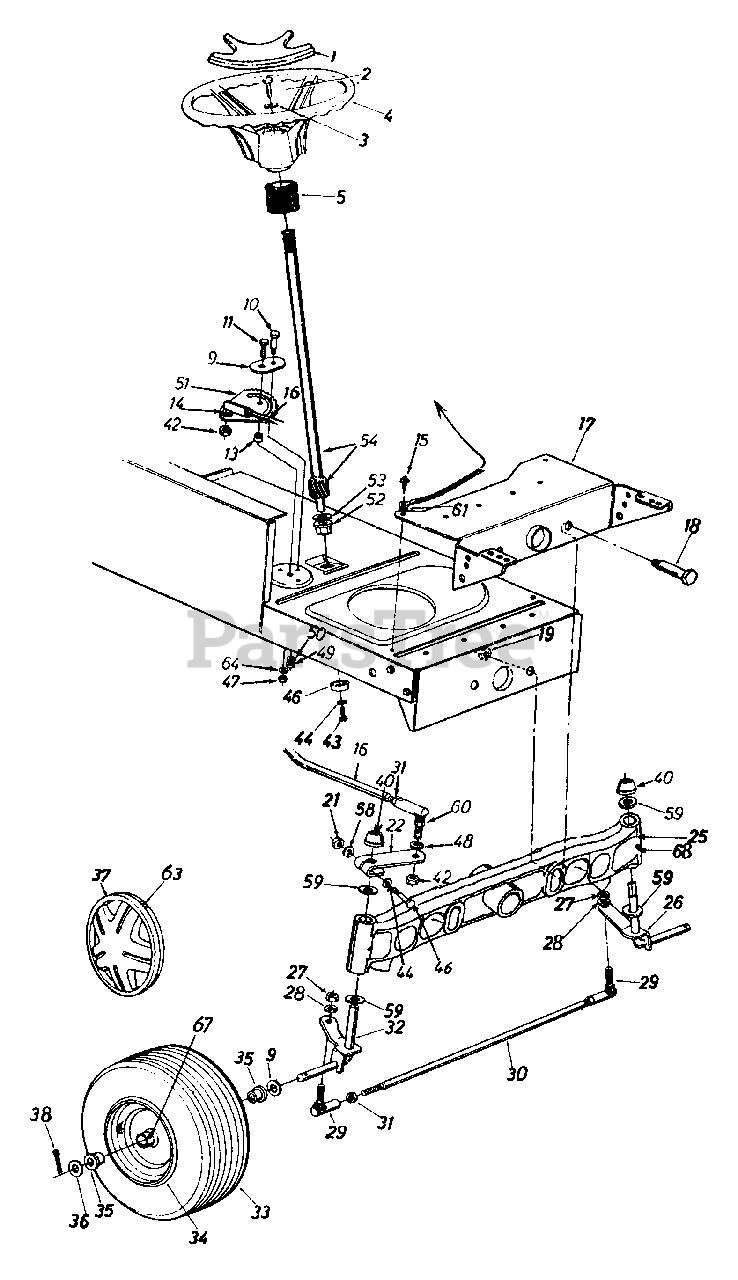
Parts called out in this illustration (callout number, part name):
1	Steering Wheel Cap
2	Hex Bolt 5/16-18 x 1" Lg.
3	Belleville Wash. .345" I.D.
4	Steering Wheel
5	Steering Bellow - 9"
9	Retainer Plate
10	Shoulder Bolt .437" Dia. x .35" Lg. - 5/16-18 Thd.
11	Hex Bolt 3/8-24 x 1.0" Lg. (Grade 5)
13	Spacer .380" I.D. x .625" O.D. x .227
14	L-Wash. 3/8" I.D. (H.D.)
15	Hex Wash. Hd. Self-Tap Scr.
16	Steering Drag Link
18	Shoulder Bolt .498" Dia. x 2.04" Lg. - 3/8-16 Thd.
19	Flanged Hex Nut 3/8-16 Thd.
21	Hex L-Nut 5/16-24 Thd.
22	Steering Arm Front Axle
25	Pivot Bar Ass'y.
26	Front Axle Ass'y. - L.H.
27	Hex Nut 3/8-24 Thd.
28	L-Wash. 3/8" I.D.
29	Ball Joint 3/8-24 Thd.
31	Hex Jam Nut 3/8-24 Thd.
32	Front Axle Ass'y. - R.H.
36	Fl-Wash. .635" I.D. x 1.59" O.D.
37	Hub Cap
38	Cotter Pin 1/8" Dia. x 1.25"
40	Push Cap 5/8" Dia. Rod
42	Hex Jam Nut 3/8-24 Thd.
43	Torx Bolt 5/16-18 x .63" Lg.
44	L-Wash. 5/16" I.D.
47	Hex Cent. L-Nut 3/8-24 Thd.
49	Hex Cent. L-Nut 5/16-18 Thd.
50	L-Wash. 5/16" I.D.
51	Steering Gear Segment
52	Hex . Flg. Brg. 5/8" I.D.
53	Fl-Wash. (Hardened)
54	Steering Shaft
58	Wave-Wash. .32" I.D. x .62" O.D.
59	Fl-Wash. (Hardened)
60	Drag Link Ball Joint 3/8-24 Thd.
61	Ext. L-Wash. 5/16" I.D.
63	Spring Clip
64	Bell-Wash. .39" I.D. x 1.38" O.D.
67	Grease Fitting
68	Grease Fitting
